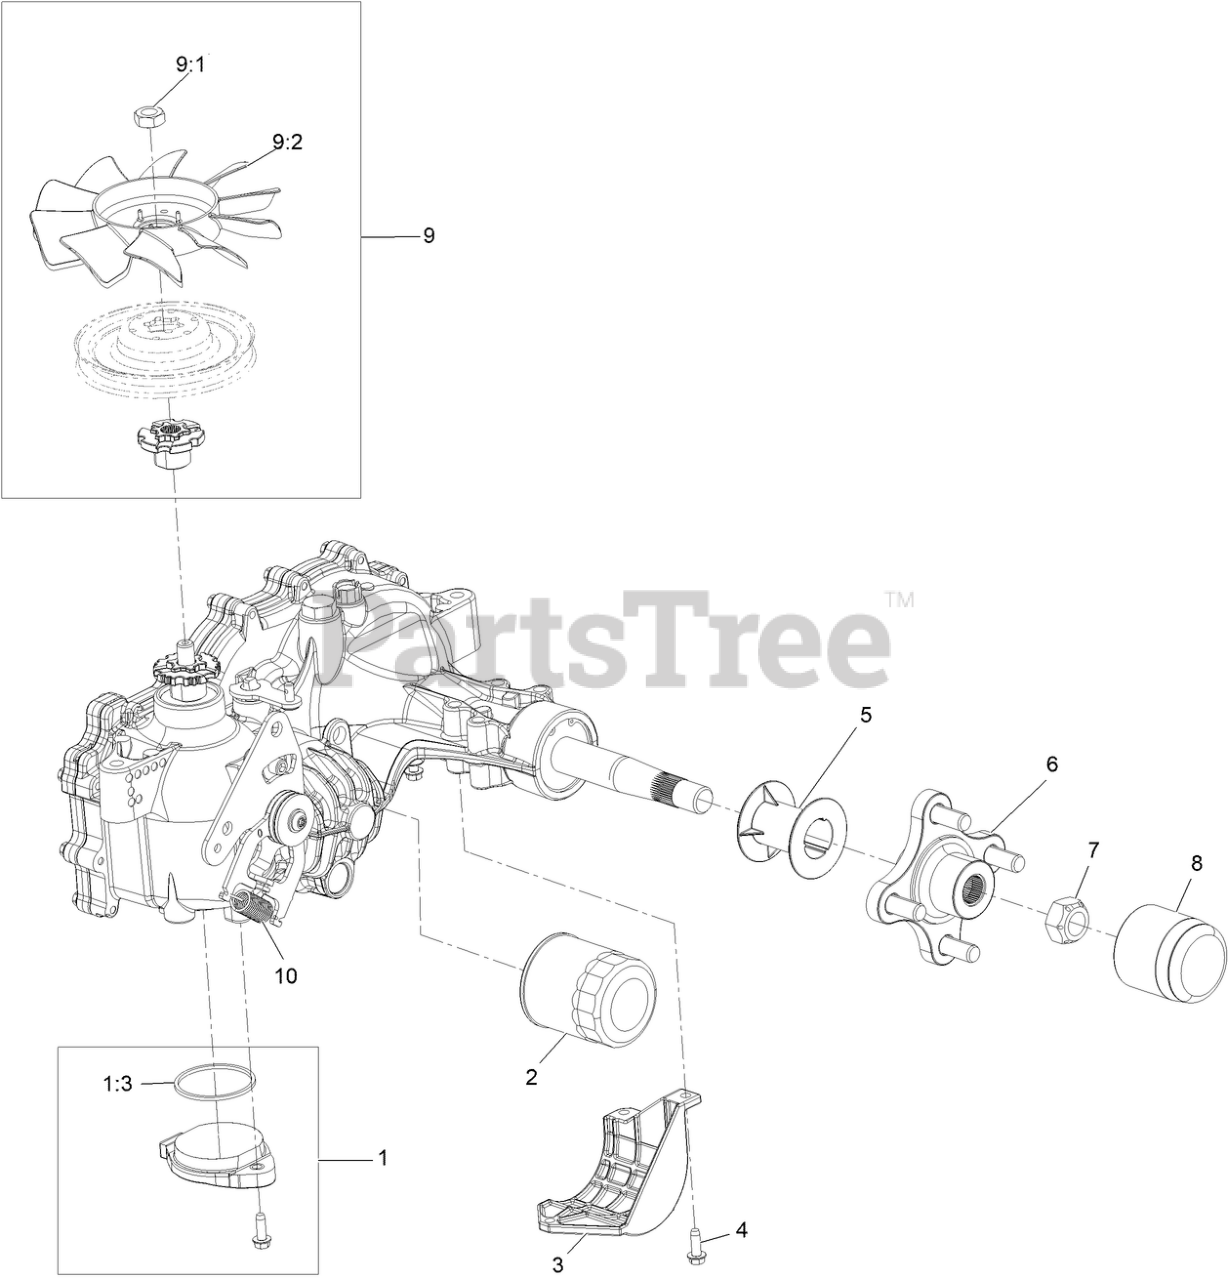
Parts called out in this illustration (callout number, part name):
1	CHARGE KIT
1:3	O RING-SEAL
2	ELEMENT-OIL FILTER, HYD
3	GUARD-FILTER, LH
5	TUBE-AXLE
6	HUB-OFFSET
7	NUT-HUB
8	CAP-AXLE, LONG
9	Fan And Pulley Kit
10	SPRING-EXTENSION
